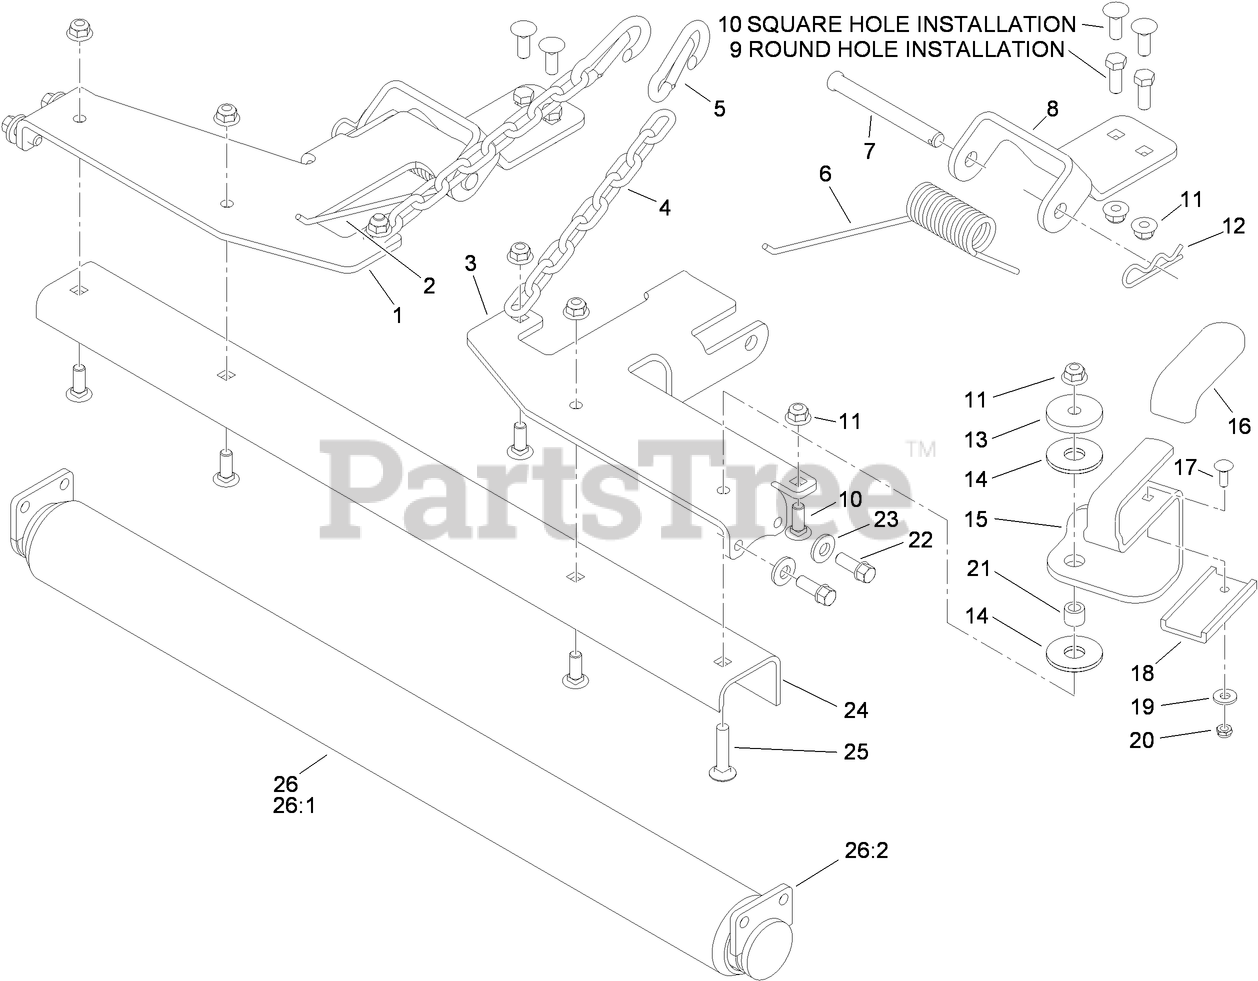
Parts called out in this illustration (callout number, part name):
1	BRACKET-MOUNTING, LH
2	SPRING-TORSION
3	BRACKET-MOUNTING, RH
4	CHAIN
5	LINK-SNAP
6	SPRING-TORSION
7	PIN-CLEVIS
8	BRACKET-MOUNTING
9	SCREW-HH
10	SCREW-CARR
11	NUT-HF, NI
12	PIN-HAIR
13	WASHER-PLAIN
14	WASHER-FRICTION, COMPOSITE
15	HANDLE-LIFT, ROLLER
16	GRIP-LEVER
17	BOLT-CARR
18	SLIDE-PLASTIC
19	WASHER-FLAT
20	NUT-LOCK, NI
21	BUSHING-LEVER, LIFT
22	SCREW-HWH
23	WASHER-BELLEVILLE
24	SCRAPER-ROLLER
25	SCREW-CARR
26	ROLLER ASM
26:1	ROLLER-STRIPER
26:2	HUB ASM
